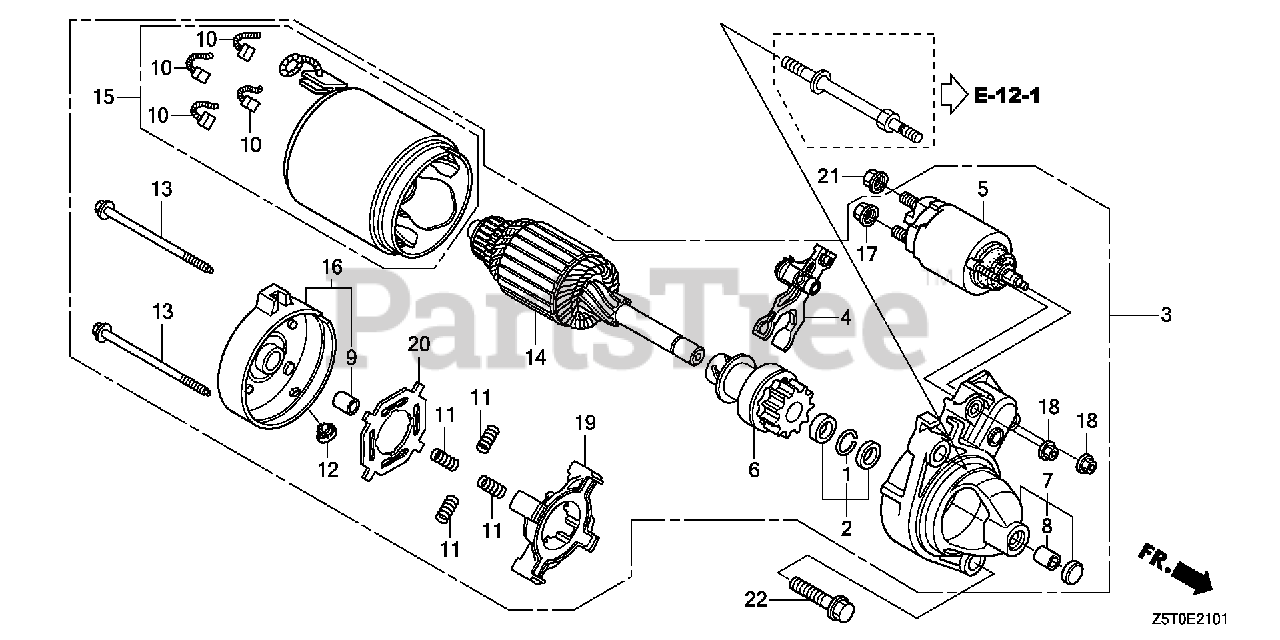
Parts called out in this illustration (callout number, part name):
1	RING, SNAP (DENSO)
2	COLLAR SET, CLUTCH STOP
3	STARTER MOTOR ASSY.
4	LEVER, PINION DRIVE
5	SWITCH ASSY., MAGNET
6	CLUTCH, OVERRUNNING
7	HOUSING, DRIVE SIDE
11	SPRING, BRUSH
13	BOLT, THROUGH
16	FRAME, COMMUTATOR END
17	NUT, HEX. (8MM)
18	NUT, HEX. (6MM)
19	HOLDER, BRUSH
20	INSULATOR, BRUSH HOLDER
21	NUT-WASHER (8MM)
22	BOLT, FLANGE (10X40)
